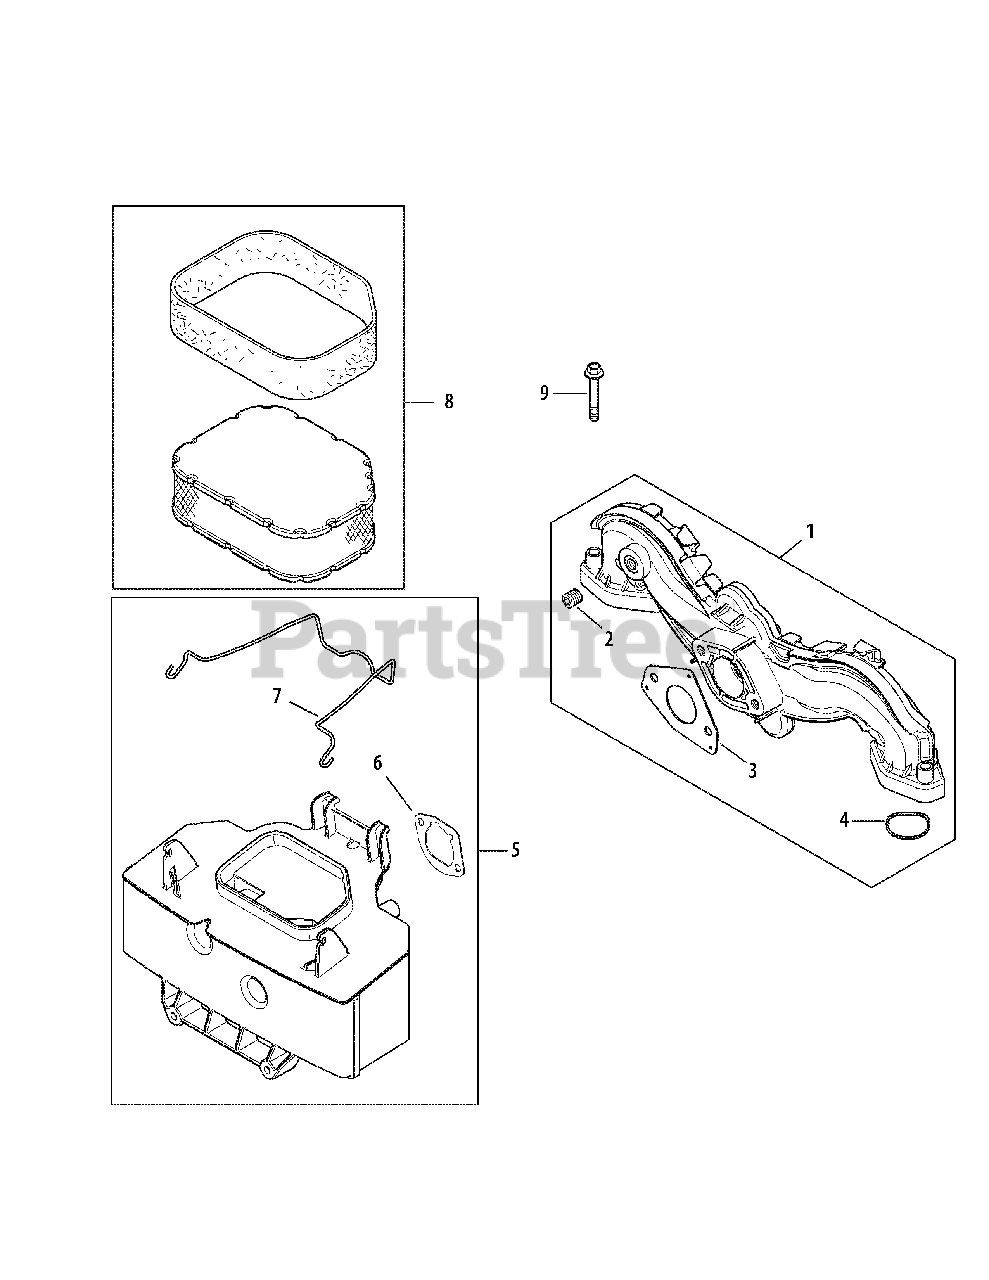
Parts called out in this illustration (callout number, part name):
1	Intake Manifold Kit (Inc. 2-4)
2	Carburetor Gasket
3	Intake Port O-Ring
4	Pipe Plug, 1/8
5	Air Cleaner Base Kit (Inc. 5 & 6)
6	Air Cleaner Base Gasket
7	Air Cleaner Element Latch
8	Air Filter Element
9	Flg. Screw, M6 X 1.0 X 40
10	Pre-Cleaner Element
